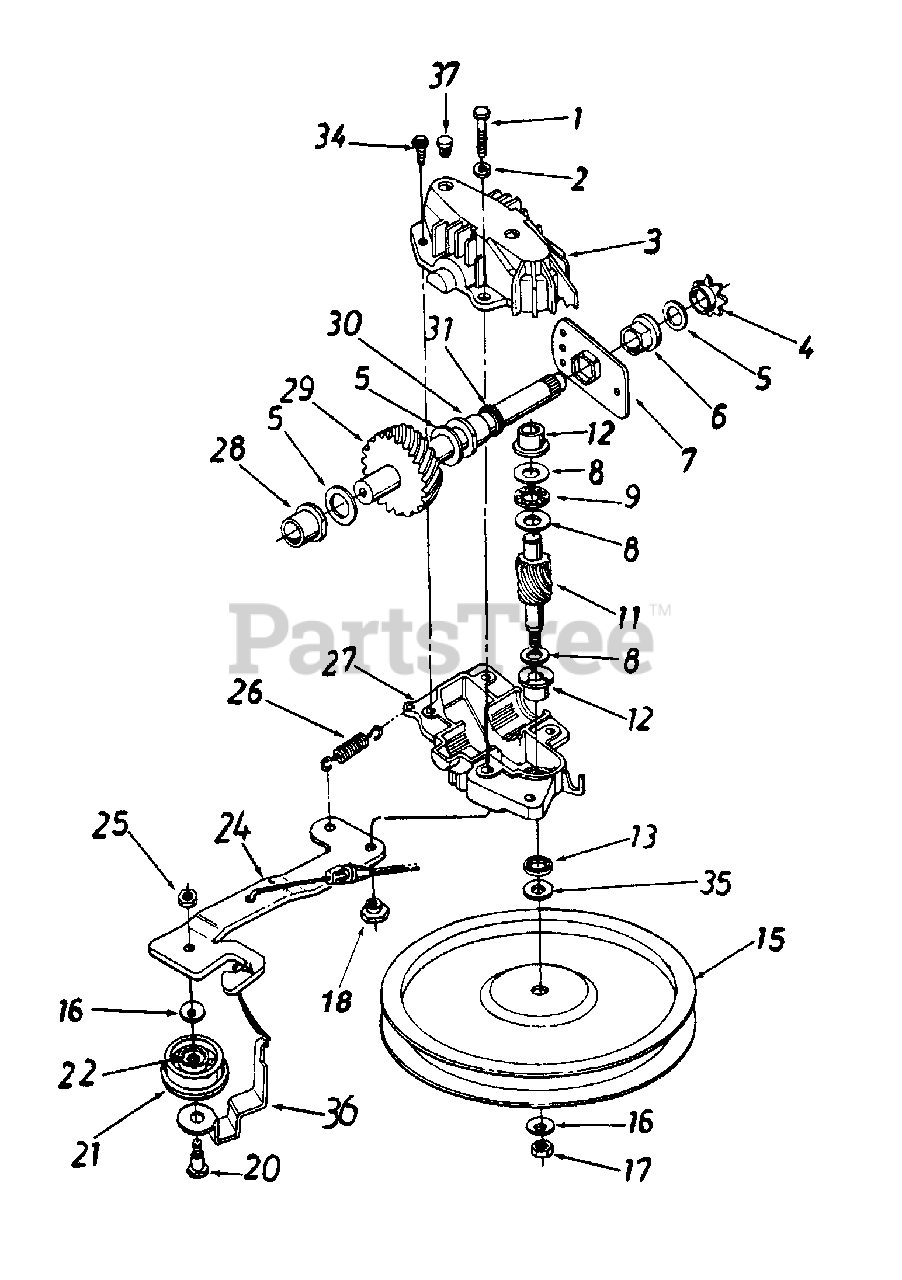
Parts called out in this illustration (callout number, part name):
1	Hex Bolt 1/4-20 x 1.25" Lg.
2	L-Washer 1/4" I.D.
3	Upper Hsg. Half
4	#48 Sprocket 7 Tooth x 1/2 Pitch
5	Fl-Wash. 5/8" I.D. x .030"
6	Hex Flange Brg. .631" I.D.
8	Thrust Wash. .382" I.D. x .70 O.D.
9	Thrust Brg. .375" I.D. x .812" O.D.
11	11 Tooth Pinion Shaft
12	Flange Bearing
13	Oil Seal
15	Fl-Pulley 5.06" O.D.
16	Bell-Wash. .265" I.D. x .75"
17	Hex L-Nut 1/4-28 L.H. Thd.
18	Shld. Spa. .375" x Dia. x .170
20	Shld. Bolt .375" Dia. x .40"
21	Fl-Idler Plastic 1.50" Dia.
22	Needle Brg. .375" x .31"
24	Idler Brk't Ass'y.
25	Hex Patch L-Nut 1/4-28 Thd.
26	Extension Spring 1.12" Lg.
27	Lower Hsg. Half
28	Flange Bearing .566" Dia.
29	Shaft Ass'y.
30	Flange Bearing .629" Dia.
31	Oil Seal .625" Dia.
34	Hex B-Tap Scr #10-16 x .75"
35	Hex Washer .26" x .88"
36	Belt Keeper
37	Plug 1/4" x .437"
